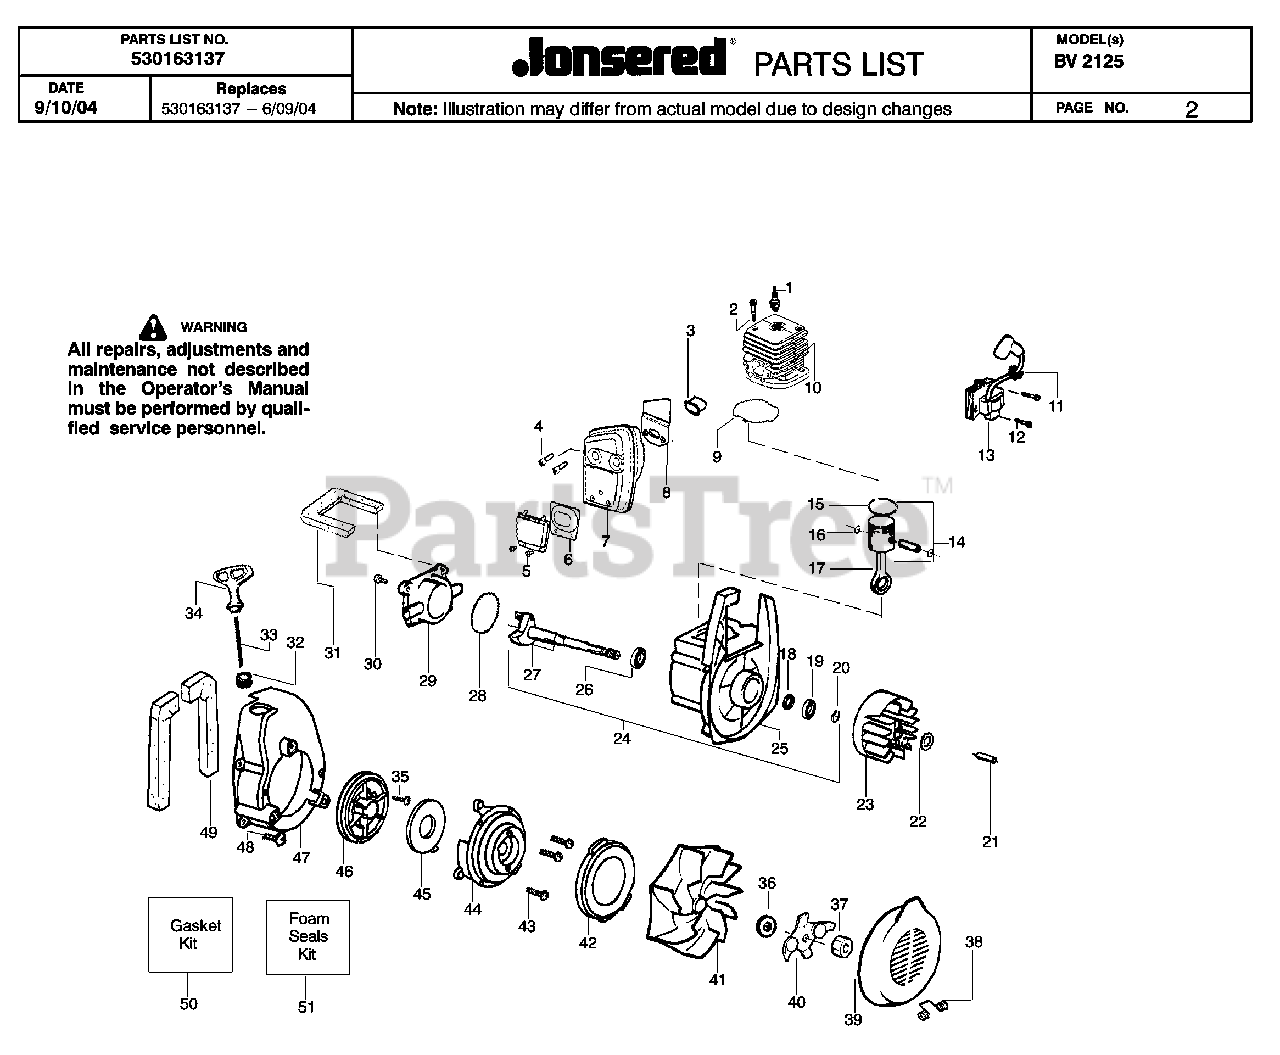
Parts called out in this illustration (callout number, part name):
1	PLUG-SPARK (RCJ-6Y)
4	SCREW 1/4-20 X .813
5	SCREW-6-19X5/16PLAST PA
8	GASKET KIT
9	GASKET KIT
14	PISTON KIT
15	PISTON RING
16	WRIST PIN RET.
18	KIT-CRANKCASE SEAL
19	OUTER BEARING
20	RETAINING RING
23	FLYWHEEL ASS'Y
26	BEARING
28	GASKET KIT
30	SCREW - SHROUD
32	EYELET-FLANGE
35	SCREW SEMS TOOTHED WASHER
43	SCREW FILTER PLATE
45	SPRING
46	PULLEY
48	SCREW - SHROUD
50	GASKET KIT
